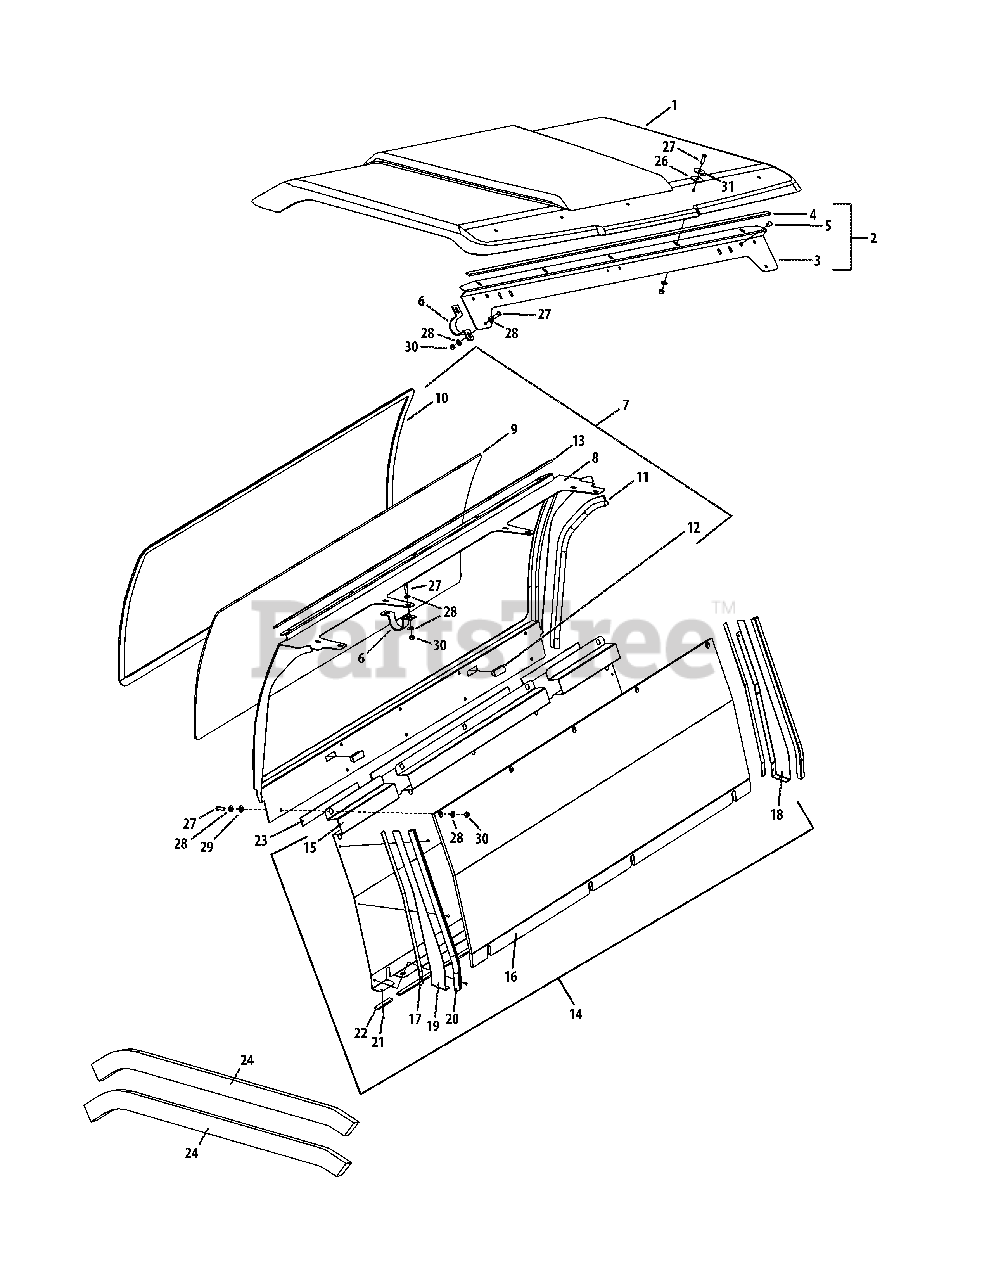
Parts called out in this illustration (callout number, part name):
1	Roof Assembly Cub Cadet Volunteer
2	Roof Support Front (Includes Ref. 3-5)
3	Front Roof Mount
4	1/2" V-Groove Weatherseal
5	Dome Plug, 7/16", Heyco #2633 "Small" (Bag - 15)
6	Upper Mounting Bracket-Rev C (Set Of 6)
7	Rear Panel Assembly - Txtrd. Black (Incl. Ref. 8-13)
8	Rear Panel Frame
9	Rear Window
10	Window Mounting Rubber, 20'
11	Standard Bulb Rubber (5/8")
12	2" x 3/4" Hole Plug
13	1/2" V-Groove Weatherseal
14	Rear Panel Bottom Assembly (Includes Ref. 15-22)
15	Rear Panel Bottom
16	Foam Panel
17	1/2" Foam Tape
18	Rear Panel Bottom Left Side
19	Rear Panel Bottom Right Side
20	Side Bulb Rubber, 3/4"
21	Rivet
22	1/2" V-Groove Weatherseal
23	Foam Seal, 1" X 1/8
24	Expand-A-Foam, 2"
26	Hardware Kit - 5/16 Foam Rubber Washer
27	Hardware Kit - 5/16-18 x 1" Bolt
28	Hardware Kit - 5/16" Steel Washer
29	Hardware Kit - 5/16" Nylon Washer
30	Hardware Kit - 5/16-18 Locknut
31	Hardware Kit - Fender Washer
